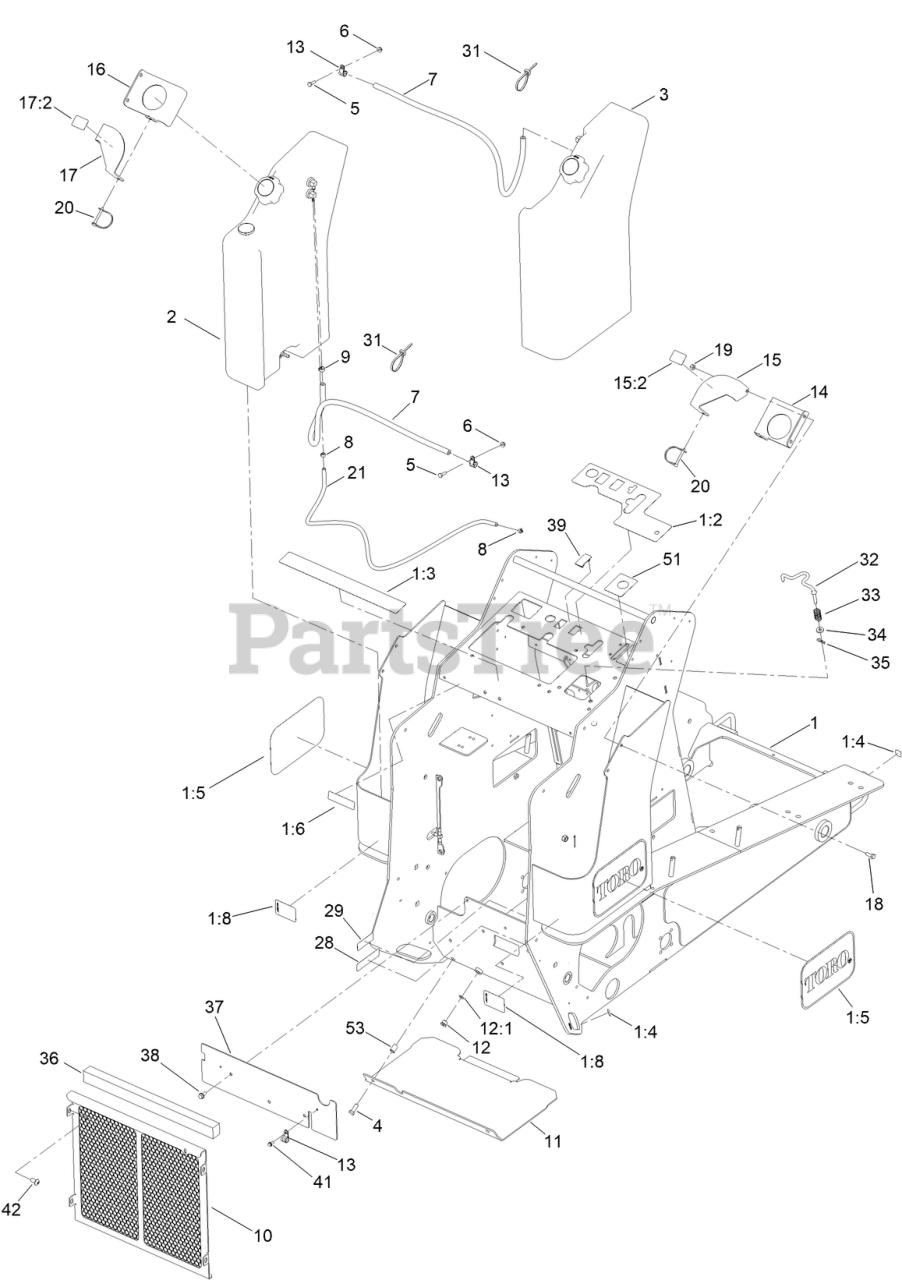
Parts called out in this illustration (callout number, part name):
1	TX1000 FRAME ASM (SERVICE)
1:2	DECAL-CONTROL PANEL
1:3	DECAL-SAFETY
1:4	DECAL-POINT, LIFT
1:5	DECAL
1:6	DECAL-RADIATOR FILL
1:8	REFLECTOR
2	LH FUEL TANK ASM
3	RH FUEL TANK ASM
4	SCREW-HH
5	SCREW-HH
6	NUT-HF
7	HOSE-FUEL
8	CLAMP-HOSE
9	CLAMP-HOSE
10	SCREEN ASM
11	COVER-BOTTOM
12	PLUG-HEX, HOLLOW
12:1	O-RING
13	CLAMP-R
14	PLATE-HOLD DOWN, RH
15	PLATE-LOCK, FUEL CAP, RH
15:2	DECAL-ULTRA LOW SULFUR DIESEL
16	PLATE-HOLD DOWN, LH
17	PLATE-LOCK, FUEL CAP, LH
17:2	DECAL-DIESEL
18	SCREW-HH
19	NUT-LOCK, NI
20	PIN-HITCH
21	HOSE-FUEL
28	DECAL-ARRESTOR, SPARK
29	DECAL - REGULATORY CE DECAL
31	TIE-CABLE
32	ROD-INTERLOCK
33	SPRING-CONTROL
34	WASHER-FLAT
36	SEAL-FOAM
37	PANEL, FRAME
38	SCREW-HWHTF
39	PLUG-HOLE
41	SCREW-HWH
42	SCREW-HH
51	DECAL-IGNITION SWITCH
53	NUT-CLINCH
